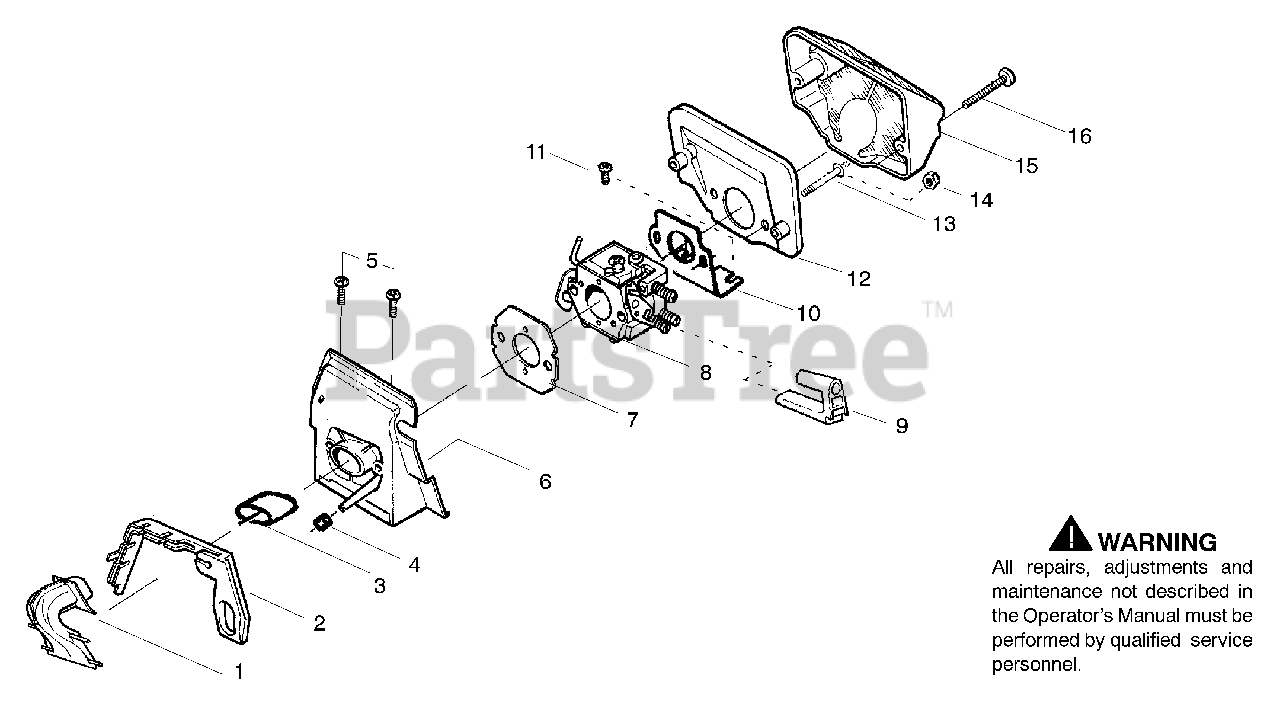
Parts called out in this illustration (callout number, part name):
1	Assy-Turbo Air Cleaner
2	Seal - Turbo Clean
3	Sleeve-Intake
4	Seal-Impulse
6	Adapter - Carb.
7	Gasket-Carburetor
8	Carburetor-W-29
9	Grommet-Final
10	Plate - Support
12	Air Filter - Bottom
13	Stud - Carb.
15	Air-Filter - Top
